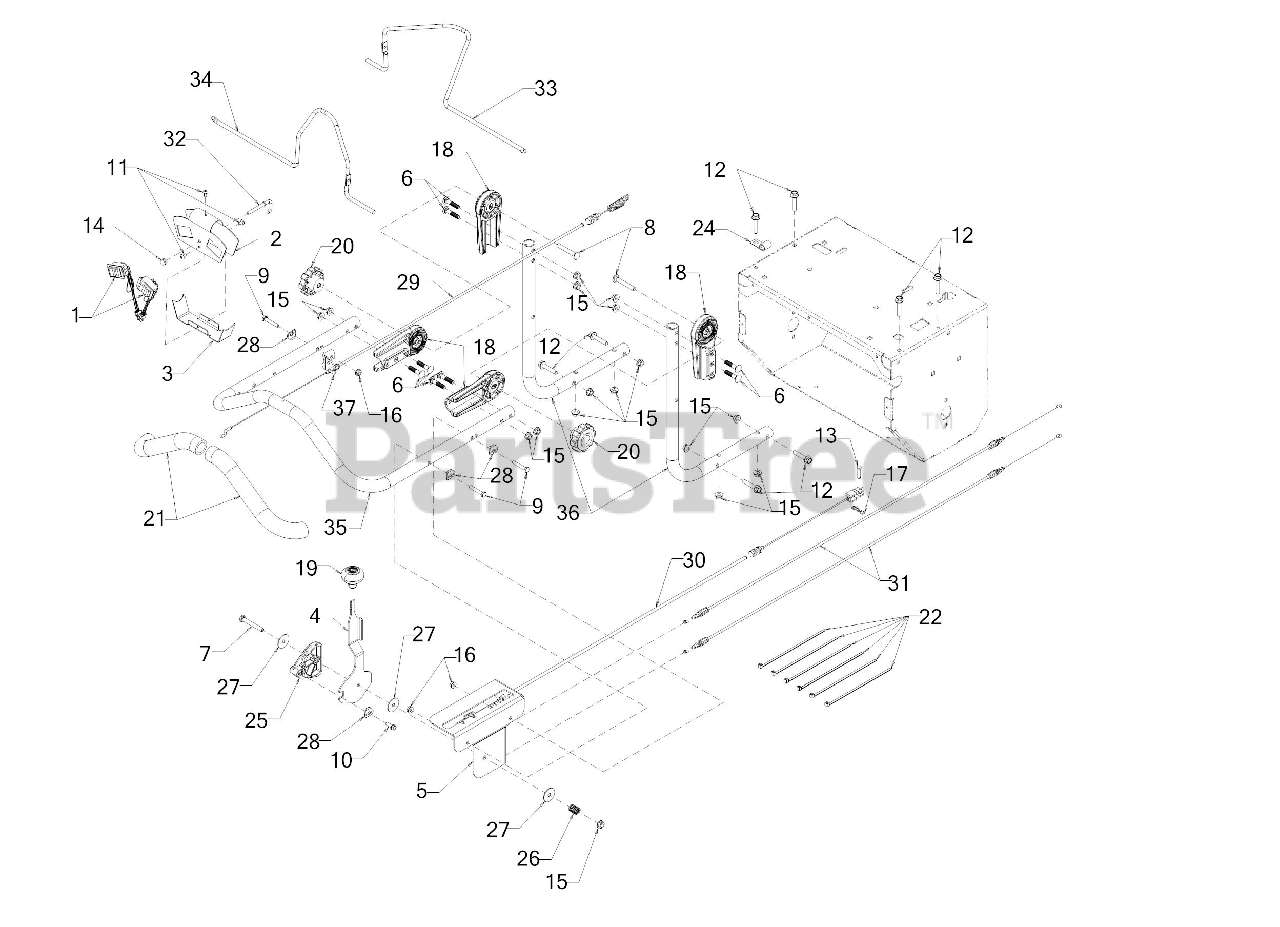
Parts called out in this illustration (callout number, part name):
1	CONTROL SWITCH ASSEMBLY
2	SWITCH MOUNTING BRACKET
3	SWITCH COVER BLOWER
4	SPEED CONTROL LEVER
5	SPEED CONTROL BRACKET
6	CARRIAGE BOLT 5/16-18 x 1.50
7	HEX SCREW 5/16-18 x 2.25 GR5
8	SCRE W5/16-18 x 2.25 GR5
9	SCREW 1/4-20 x 1.50 GR.5
10	SCREW 1/4-15 x .750
11	TORX SCREW #10-16 - .500
12	SCREW 5/16-18 x 1.50 GR5
13	CLEVIS PIN .25 x 1.00
15	FLANGE NUT
16	LOCK NUT 1/4
17	BOW TIE COTTER PIN 1/4-5/16
18	HANDLE ADJUST
19	SHIFT KNOB
20	KNOB-5/16-18
21	UPPER HANDLE GRIP
22	7" CABLE TIE
24	J TYPE CLIP
25	CABLE GUIDE
26	COMPRESSION SPRING
27	FLAT WASHER .322 ID x 1.25 x .060
28	SADDLE WASHER
29	CLUTCH CABLE
30	BRAKE CABLE
31	SPEED SELECT CONTROL CABLE
32	PARKING BRAKE HOOK ROD
33	BLOWER CLUTCH BAIL
34	BLOWER BRAKE BAIL
35	UPPER HANDLE TUBE
36	LOWER HANDLE TUBE
37	CABLE BRACKET MOUNTING (LH)
